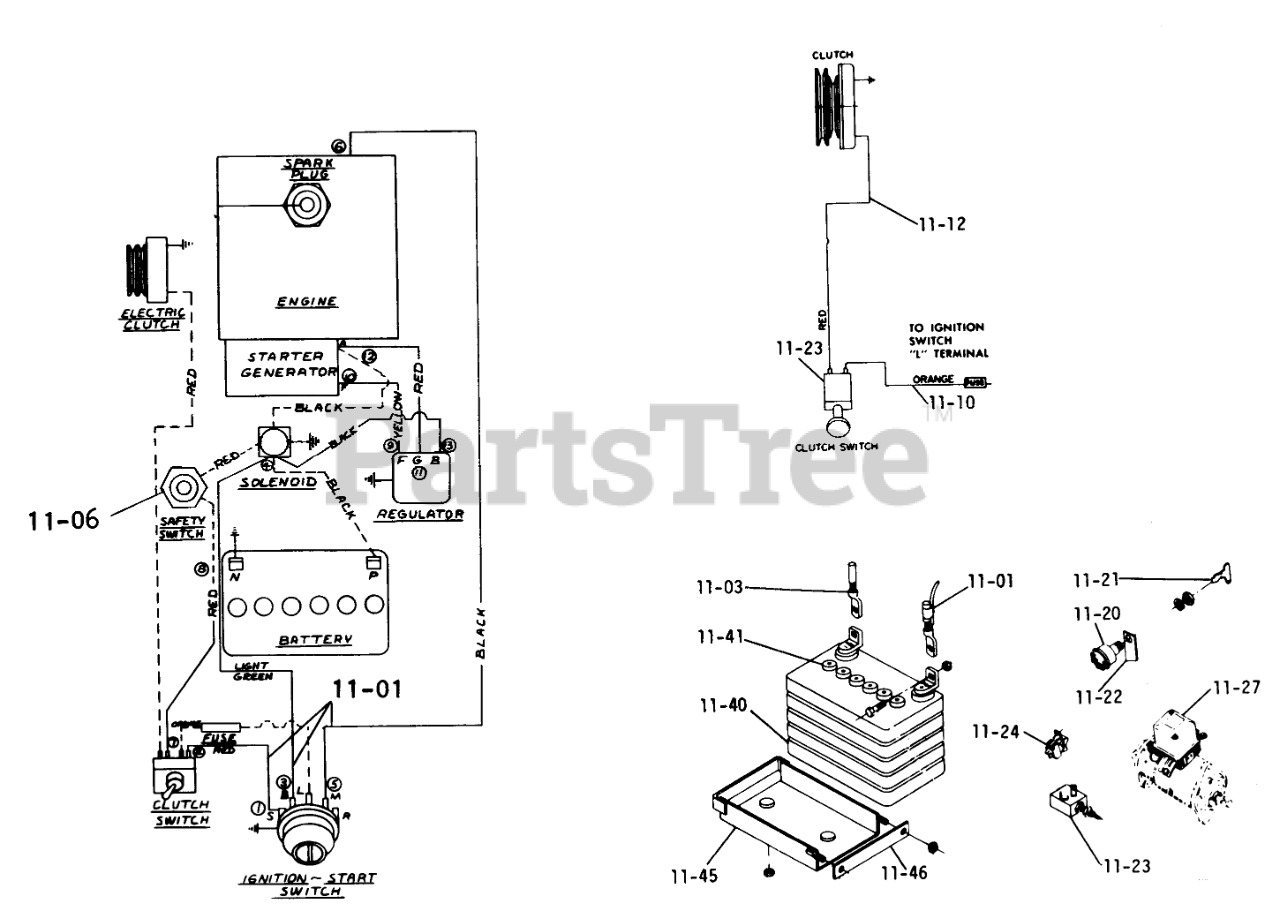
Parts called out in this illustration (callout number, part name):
11-06	SWITCH SAFETY
11-06	Bolt 3/8-16 x 1
11-06	NUT-SPECIAL 9/16-18
11-12	Lockwasher
11-20	ASSY-SWITCH IGNITION
11-20	Lockwasher 5/8
11-22	CONTROL PROTECTOR
11-27	Strap, regualtor mounting
11-45	Nut-Nylok
11-46	Nut-Nylok
11-46	Bushing (Oilite)
11-46	Bolt, 1/4-x 1/2
11-46	Nut, 1/4-20 E.S.
